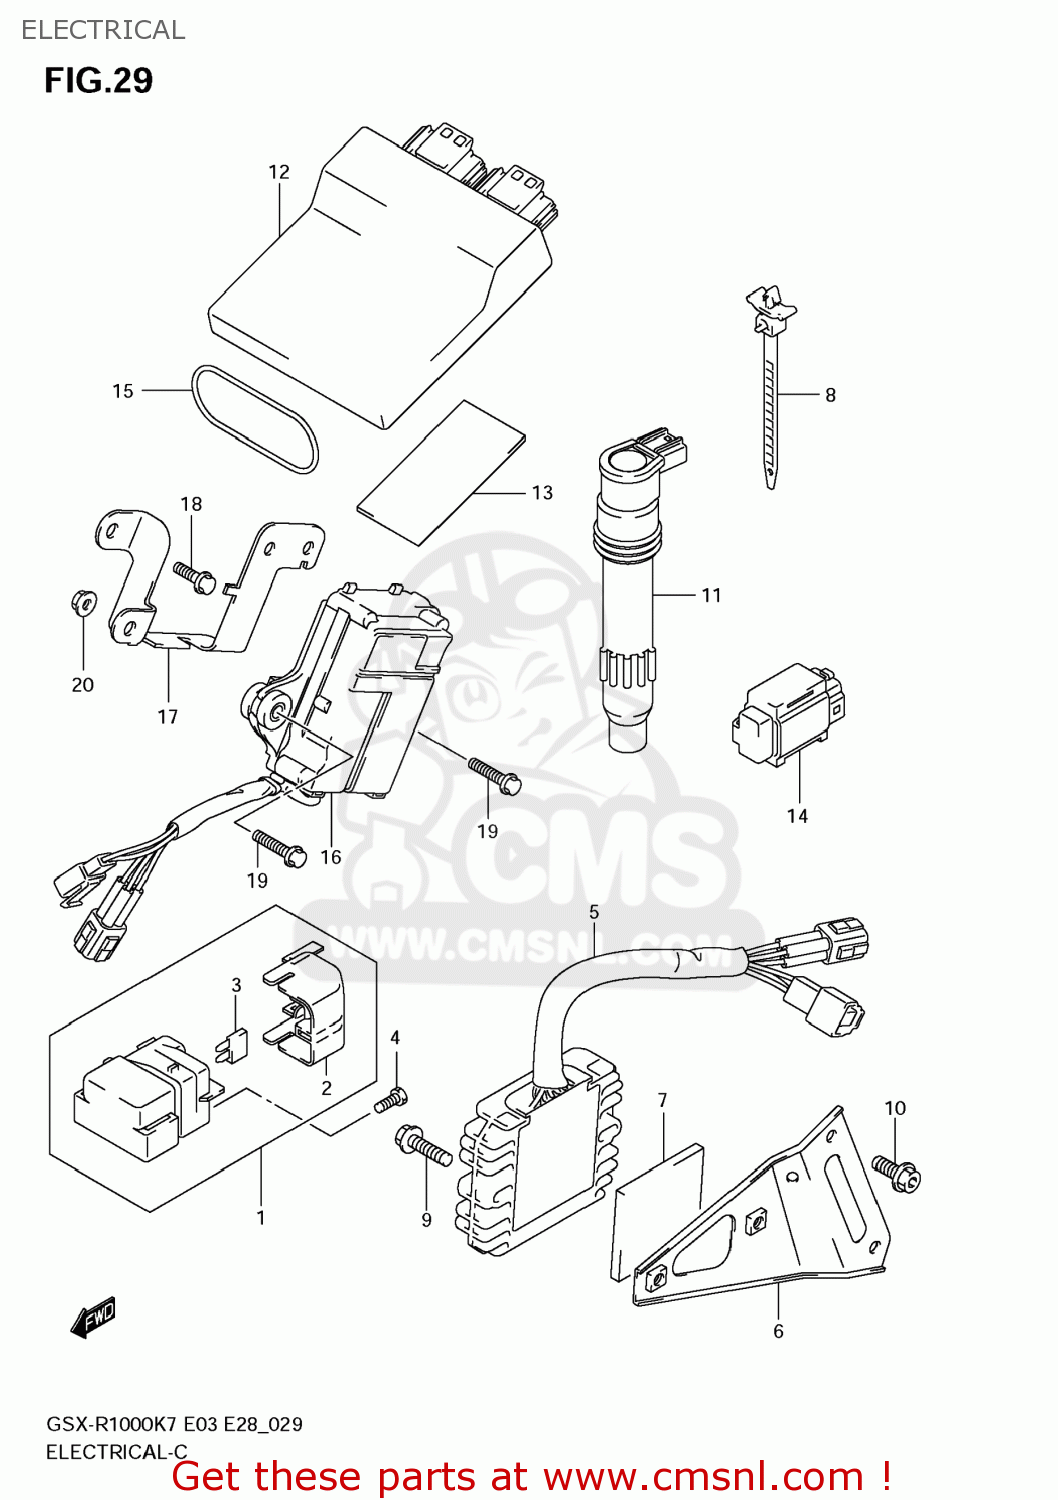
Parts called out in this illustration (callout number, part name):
1	RELAY ASSY,STARTING MOTOR
2	COVER
3	FUSE(30A)
4	SCREW(6X8)
5	RECTIFIER ASSY
6	BRACKET,RECT FTG
7	PROTECTOR(50X50X5)
8	CLAMP(L:90)
9	SCREW
10	BOLT
11	COIL ASSY,IGNITION
12	CONTROL UNIT,FI
13	PROTECTOR(80X80X2)
14	SENSOR ASSY,FUEL CUT
15	O RING(D:3.5,ID:61)
16	ACTUATOR ASSY,EXHAUST CONTROL
17	HOLDER,ACTUATOR
18	BOLT
19	BOLT
20	NUT
